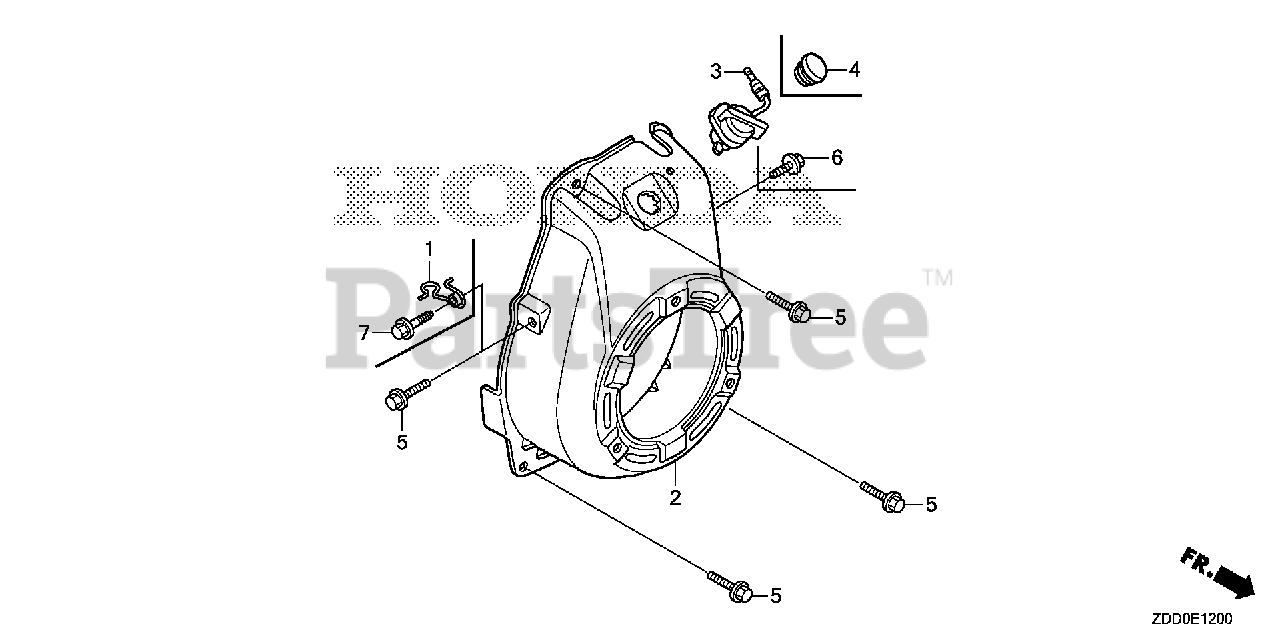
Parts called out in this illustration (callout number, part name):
2	COVER, FAN *R280* (POWER RED)
3	SWITCH ASSY., ENGINE STOP
5	BOLT, FLANGE (6X14)
